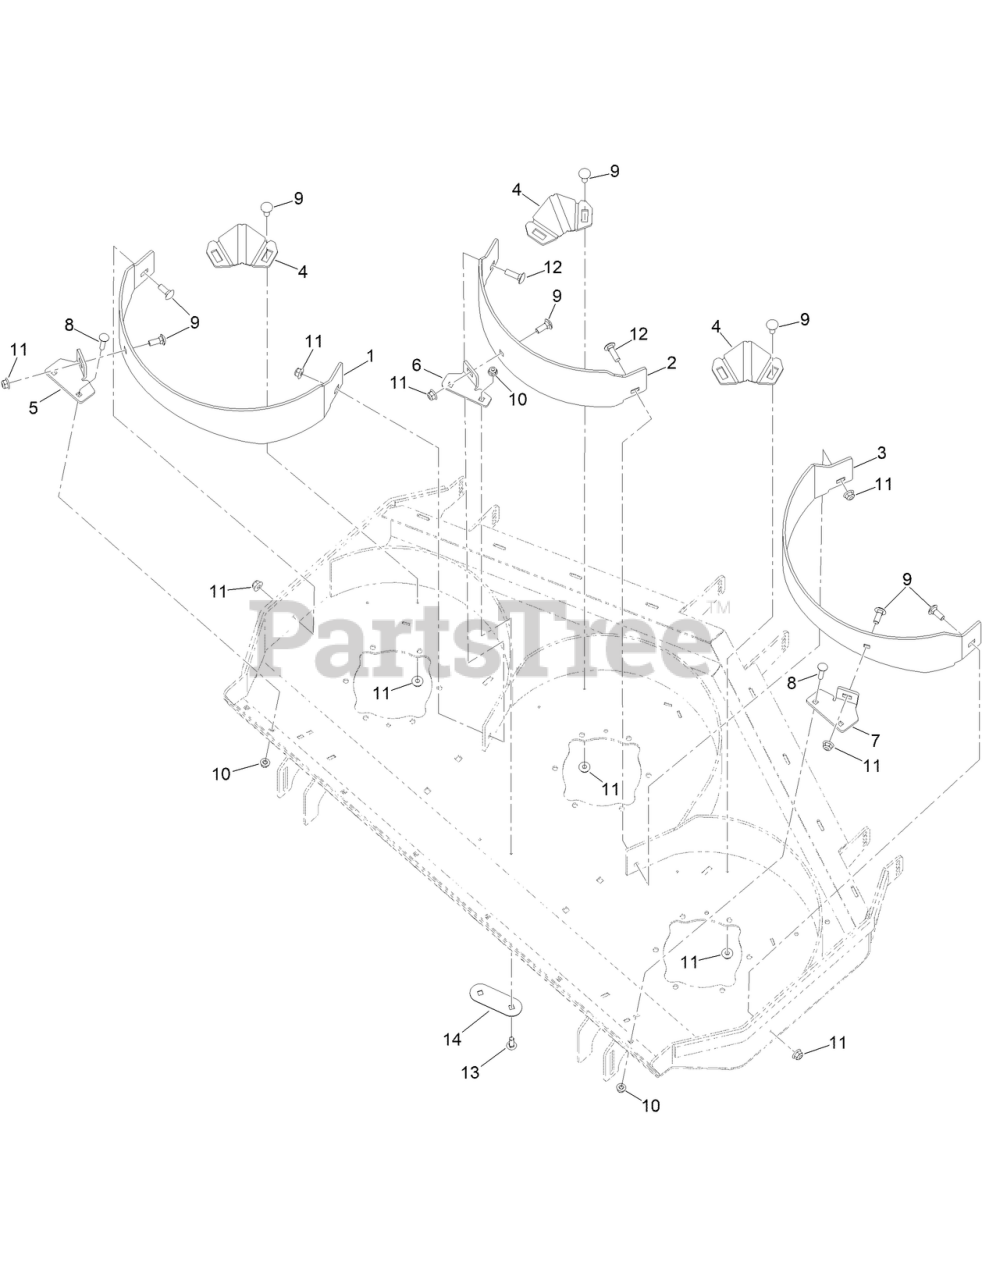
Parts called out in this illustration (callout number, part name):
1	BAFFLE-RECYCLER RH, 48
2	BAFFLE-RECYCLER, CENTER 48
3	BAFFLE-RECYCLER, LH 48
5	BAFFLE-SUPPORT, RH
6	SUPPORT, CTR BAFFLE (RD)
7	SUPPORT-BAFFLE, LH
8	SCREW-CARR
9	BOLT-CARR
10	NUT-HF, NI
11	NUT-HF, NI
12	BOLT-CARR
13	SCREW-CARR
14	SHIM-PLATE
